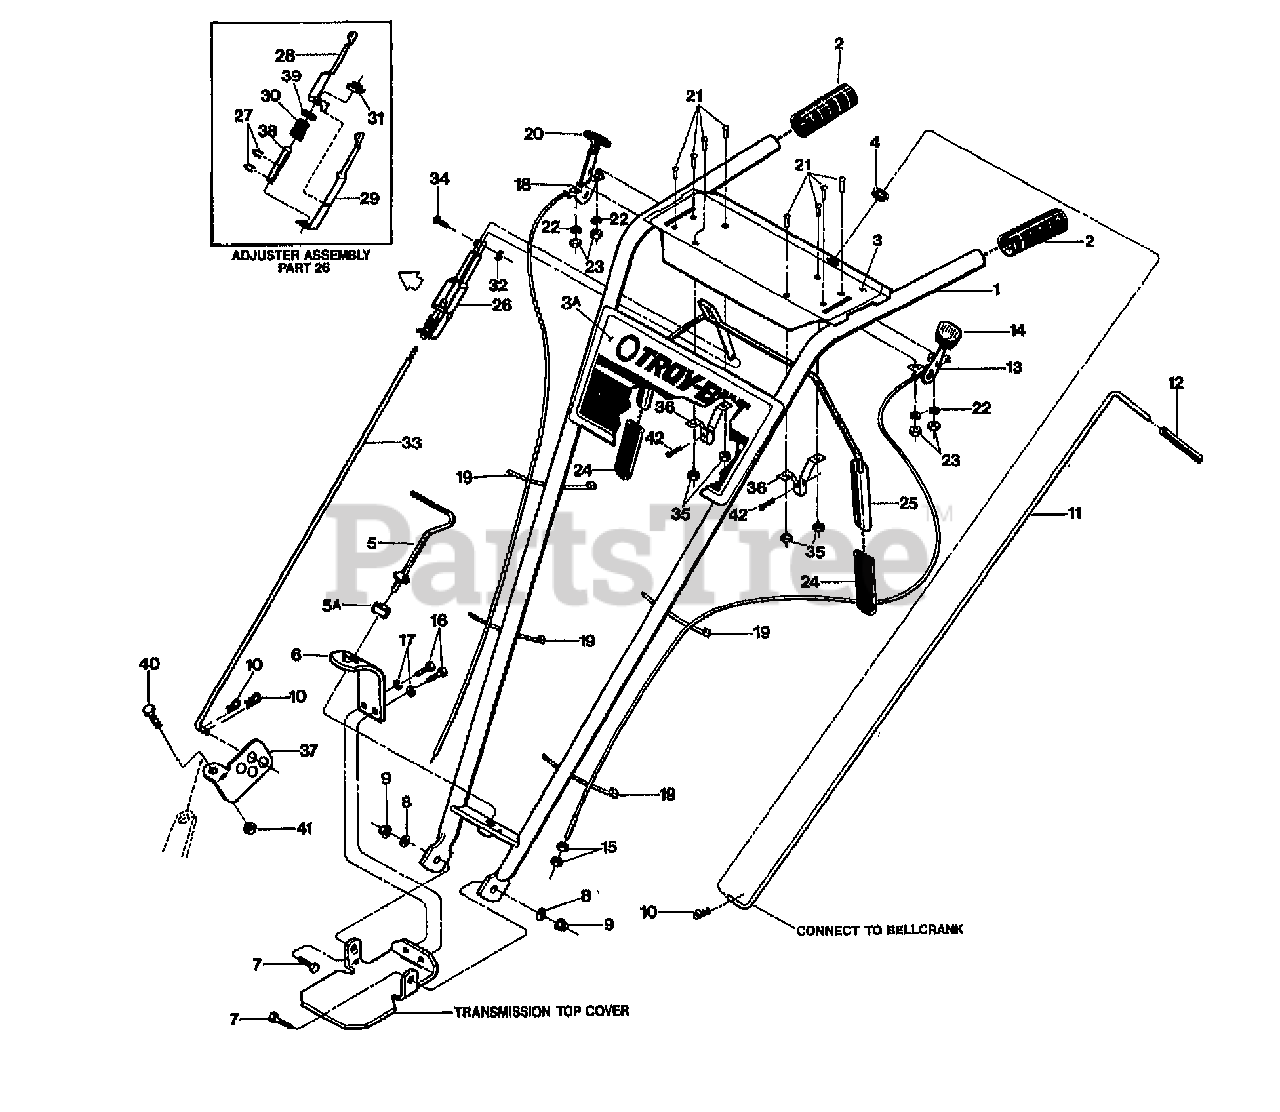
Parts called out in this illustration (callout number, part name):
1	ASSM-HANDLEBAR W/GRIPS (INCL. 2,3,3A,4)
2	GRIP-H/BAR SMOOTH
3	DECAL-CONTROL PANEL
3A	DECAL-GRAPHICS PANEL ECONO
4	BUSHING-NYLON
5	ASSM-STUD H/B
5A	WASHER-1.0X.38X.375
6	PLATE-HANDLEBAR ADJUST
7	SCR-HH 3/8-16X1.0 G5 ZP
8	WASHER-FLAT 3/8 SAE
9	NUT-LOCK 3/8-16 NYLON ZP
10	PIN-CLIP .08
11	ROD-REV W/GRIP OPC (INCL. #12)
12	GRIP-CONTROL ROD
13	CABLE-WHEEL CLUTCH OPC (INCL. 14,15,19,21-23)
14	KNOB-WHEEL DRIVE CABLE
15	NUT-HEX 5/16-24
16	SCR-HH 3/8-16X.75 G5 ZP
17	WASHER-LK .375 @ DEPL
18	CABLE-THROTTLE ECONO OPC (INCL. 20)
19	TIE-RED
20	KNOB-THROTTLE CABLE
21	SCR-RH M10-32X.5 MACH
22	WASHER-LK M10
23	NUT-HH M10-32X.125
24	GRIP-PADDLE SM FRAME OPC
25	BAIL W/GRIPS OPC (INCL. TWO #24)
26	ASSM-ADJUSTMENT OPC (INCL. 27-30,38-39)
27	RING-KLIP .500 ZINC
28	ADJUSTER-RT SIDE OPC
29	ADJUSTER-LT SIDE OPC
30	SPRING-ADJUSTER OPC
31	WELDNUT 5/16-18
32	RING-KLIP .188 DIA
33	ROD-CONTROL OPC
34	ASSM-PIN & CLIP (SMALL FRAME)
35	NUT W/LKWASHER #10-32 ZP
36	BRACKET-BAIL OPC
37	SWIVEL-SMALL FRAME
38	BUSHING-.5X.334X2.88
39	WASHER-.75X.51X.06 ZP
40	SCR-HH 1/4-20X.75 G5 ZP
41	NUT-LK 1/4-20
42	SCR-HWH 1/4-20 X .5 STH
